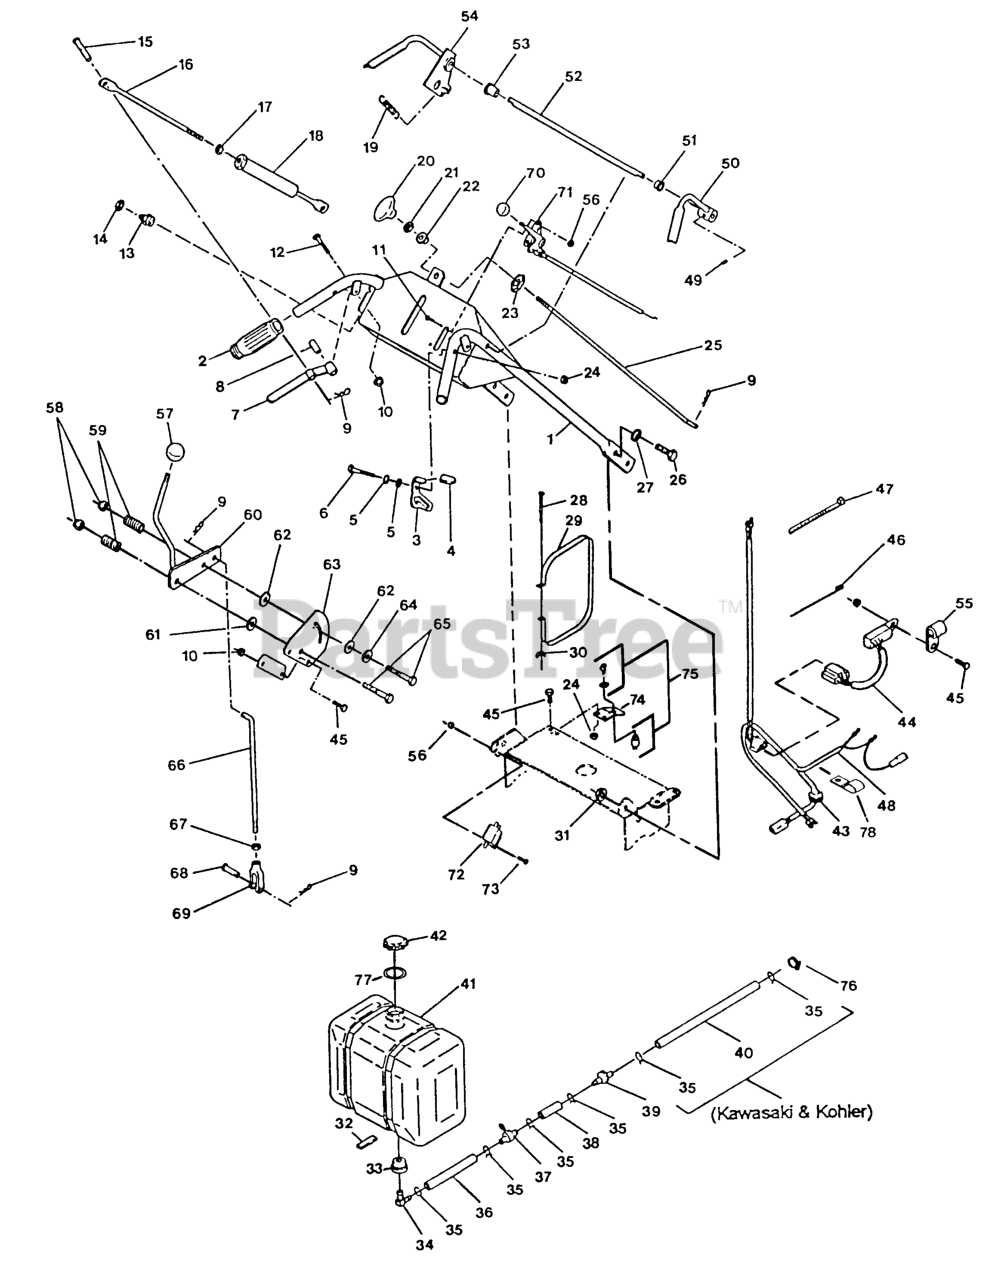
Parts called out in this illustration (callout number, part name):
3	RH LATCH W/GRIP
4	GRIP-LATCH
5	WASHER-SPRING
8	BUSHING-LEVER, DRIVE
9	PIN-COTTER
11	BOLT-CARR
13	SWITCH,OPERATOR CNTRL
15	PIN-CLEVIS
16	ROD,DRIVE LEVER LINKAGE
19	SPRING-EXTENSION
20	KNOB-PUSH / PULL
22	BEARING-NYLON
23	NUT-PUSH
25	LINKAGE-BLADE
28	SCRW,MACH CRPH
30	WINGNUT
32	PAD,PLASTIC TANK
34	ELBOW-TANK, FUEL
35	CLAMP
36	HOSE-FUEL
37	VALVE-FUEL
38	HOSE-LINE, FUEL
40	HOSE-LINE, FUEL
42	CAP-FUEL
43	GROMMET
46	TIE-CABLE
47	TIE-PLASTIC
49	SCREW-SET
51	BUSHING-NYLON
52	ROD,CONNECTING
53	BUSHING,FLANGED
55	CLIP-LOOM
57	KNOB-BALL
59	SPRING-COMPRESSION
62	WASHER-FRICTION
63	PLATE-LEVER, SHIFTER
64	WASHER-FRICTION
66	ROD,SPEED CONTROL PLTD
68	PIN-CLEVIS
69	YOKE-ADJUSTABLE
70	KNOB-BALL
71	CABLE,THROTTLE CONTROL
72	SWITCH-OPEN, NORMALLY
75	SWITCH & KEY (INCLUDES NU
76	CLAMP-HOSE
